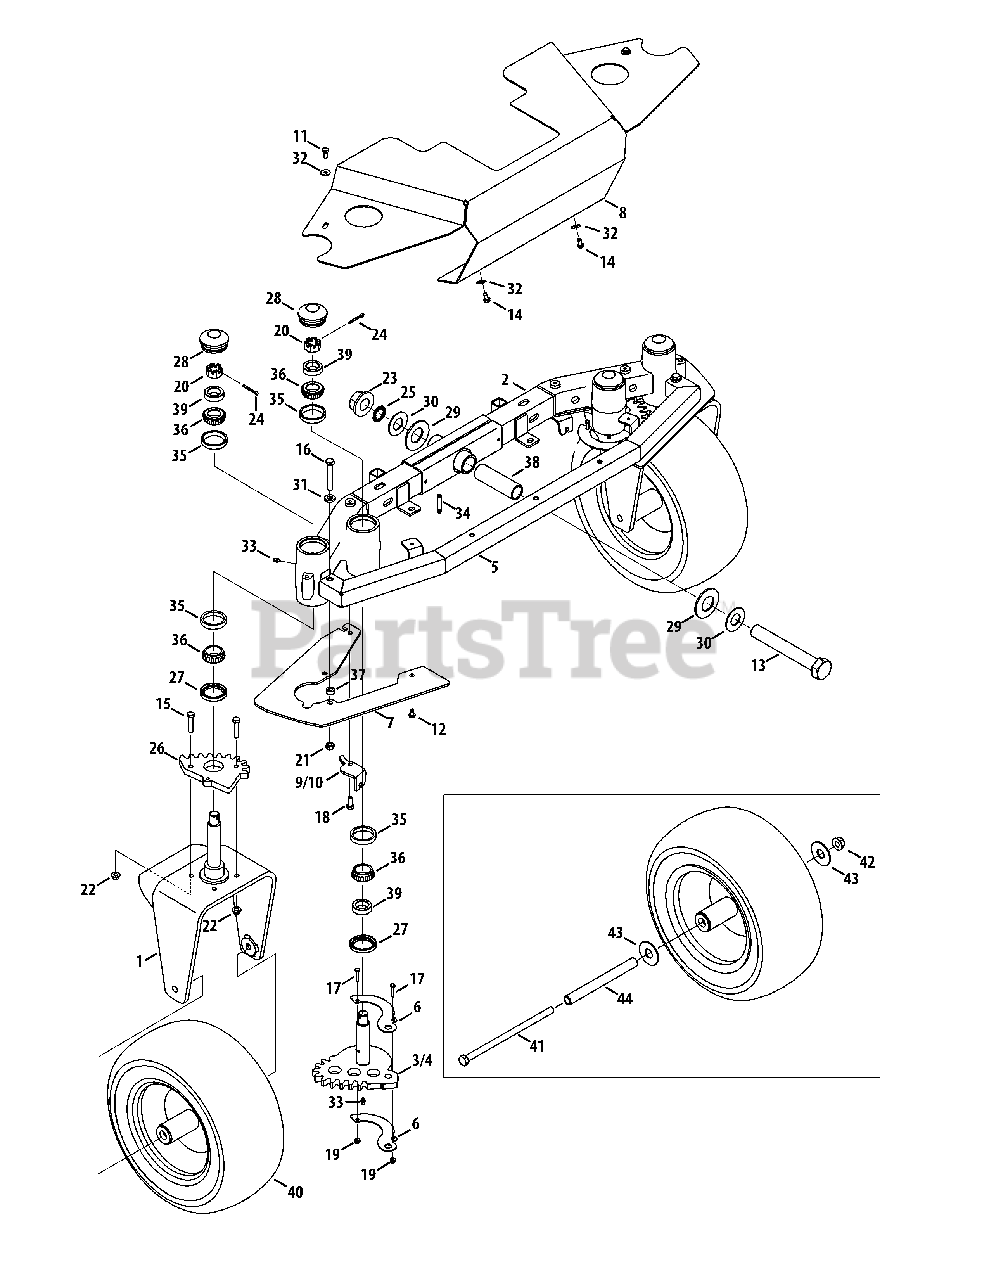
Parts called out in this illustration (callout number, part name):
1	Yoke Assembly
2	Axle Assembly
3	LH Steering Gear
4	RH Steering Gear
6	Gear Cable Mounting Bracket
7	Gear Panel Cover
9	RH Steering Cable Bracket
10	LH Steering Cable Bracket
11	Hex Cap Screw, 1/4-20 x .625
12	Screw, 1/4-20 x .5
13	Hex Cap Screw, 1-14 x 7.0
14	Hex Flange Screw, 1/4-20 x .500
15	Hex Cap Screw, 5/16-18 x 1.50
16	Hex Cap Screw, 3/8-16 x 2.50
17	Machine Screw, #10-24 x 1.00
18	Hex Cap Screw, 5/16-18 x .75
19	Nut, #10-24, Hexlock
20	Nut, 3/4-16, Slotted
21	Nut, 3/8-16, Hexlock
22	Nut, 5/16-18, Flangelock
23	Nut, 1.0-14, Flangelock
24	Cotter Pin, 5/32 x 1.25
25	Retainer Ring
26	Steering Gear
27	Seal, 14858
28	Axle Grease Cap
29	Bell Washer, 1.25 x 2.50 x .180
30	Washer, 1.00 x 2.00 x .075
31	Washer, .407 x .812 x .135
32	Washer, .260 x .720 x .060
33	Grease Fitting, 1/4-28
34	Grease Fitting, 1 39/64
35	Cup Bearing
36	Cone Bearing
37	Spacer, .380 x .625 x .265
38	Spacer, 1.005 x 1.247 x 4.1
39	Spacer, 1.00 x 1.50 x .437
40	Wheel Assembly, 15 x 6.5-8
41	Hex Cap Screw, 1/2-13 x 9.5
42	Nut, 1/2-13, Flangelock
43	Washer, .781 x 2.00 x .105
44	Spacer, .51 x .750 x 7.38
